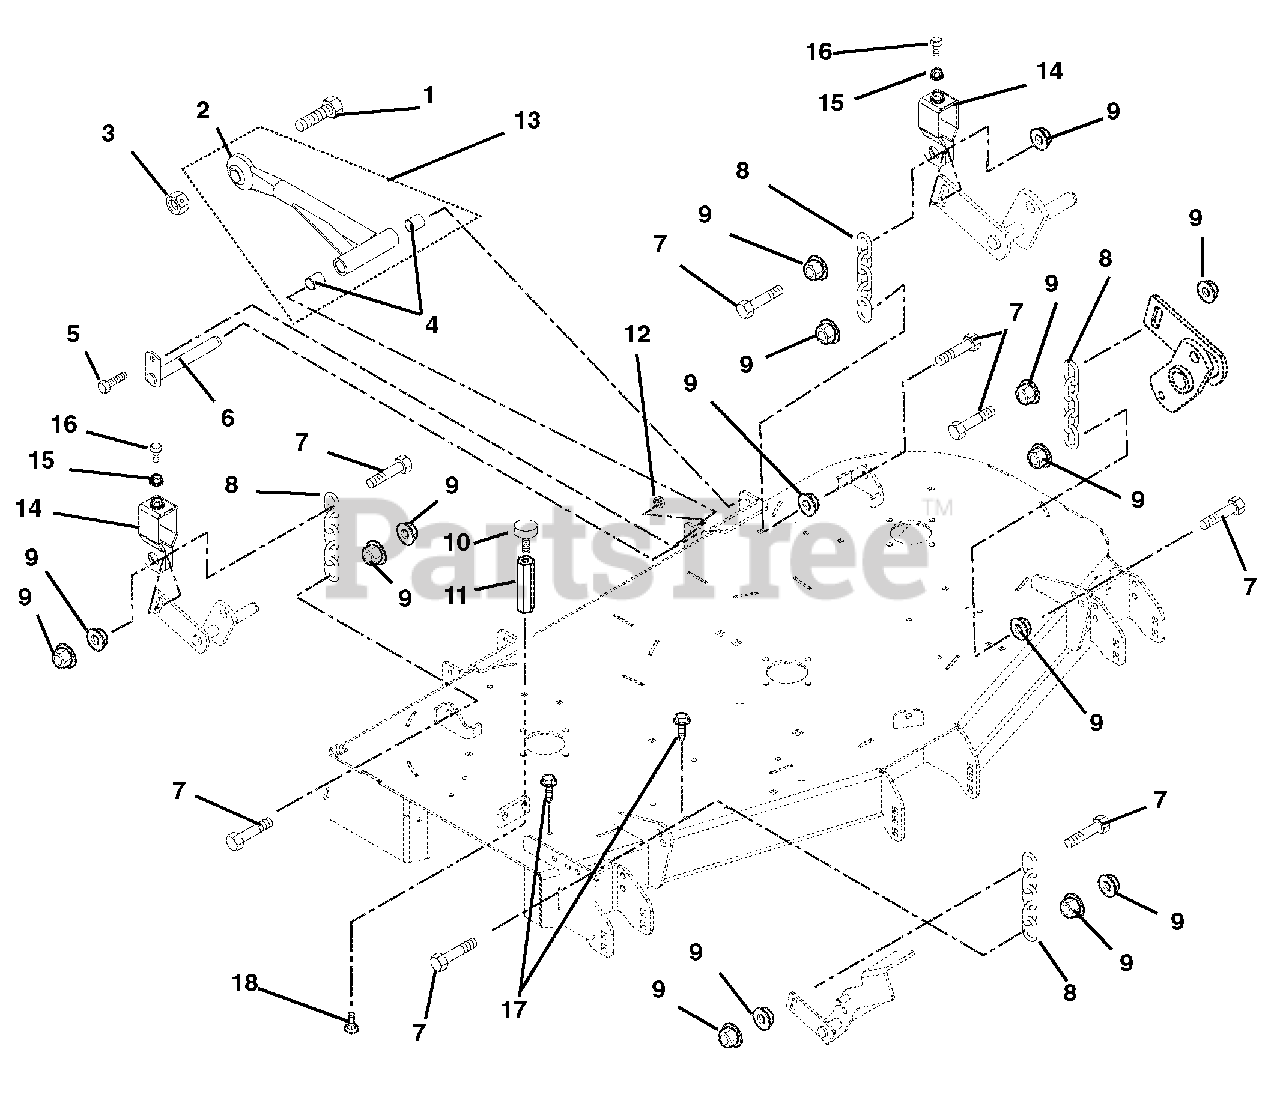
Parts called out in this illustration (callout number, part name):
1	Bolt, Hex .875-9 x 2.75 Grade 5
2	Mower Mounting Arm Weldment
3	Nut, Locking-Center .875-9
4	Bearing, .75 x .875 x 1.00
5	Bolt, Hex .38-16 x 1.00 Grade 5
6	Weldment, Mower Mounting Pin
7	Bolt, Hex M12-1.75 x 50 Grade 5
8	Chain, Link
9	Nut, Locking-Top-Flange M12-1.75
10	Bumper, Rubber
11	Nut, Coupling .31-18 x 3.00
12	Nut, .38-16 Nyloc Flange
13	Assembly, Mower Mounting Arm (Includes item # 2 and item # 4)
14	Bracket, Deck Leveling
15	Nut, Jam .312-18
16	Bolt, Hex .31-18 x 2.00 Full Thread
17	Screw, Tapping .38-16 x .50 Hex Washer Head Thread (991026, 027, 029, 032)
18	Bolt, Round Head Square Neck .31-18 x .75 Loctite
